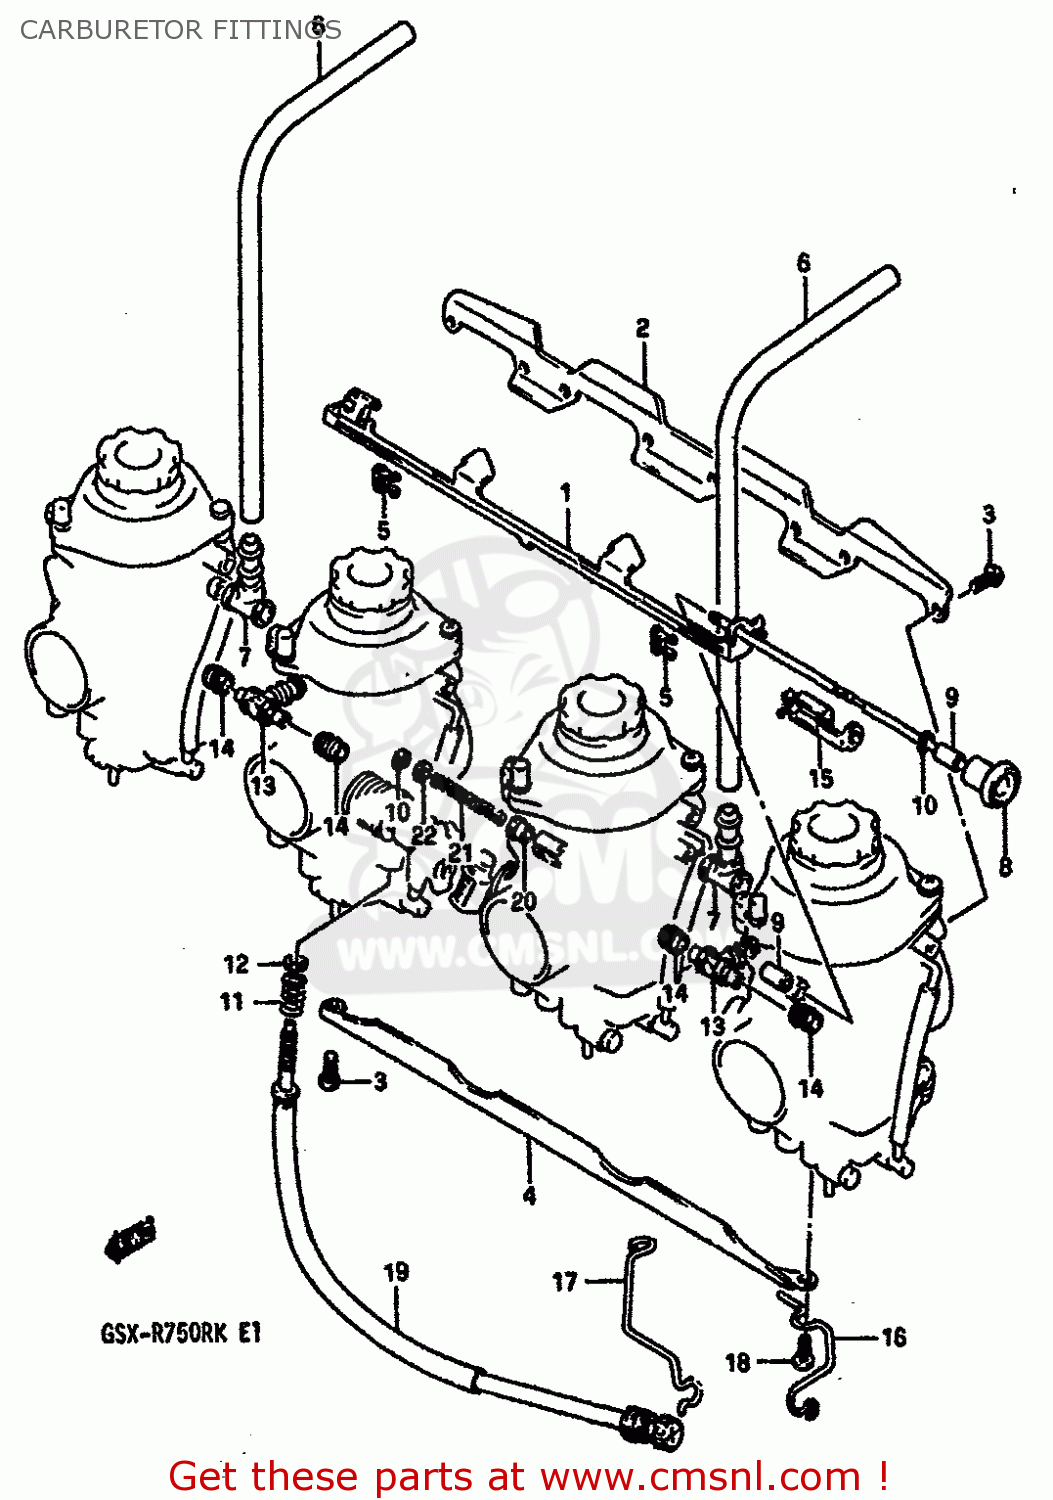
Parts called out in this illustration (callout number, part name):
1	LEVER
2	PLATE
3	SCREW
4	PLATE
5	HOLDER
6	HOSE
7	HOSE
8	SHAFT ASSY,STARTER
9	SPACER
10	E RING
11	SPRING
12	WASHER
13	NIPPLE
14	SEAL
15	PLATE
16	CLIP
17	CLIP
18	SCREW
19	ADJUSTER
20	RING
21	SPRING
22	WASHER
